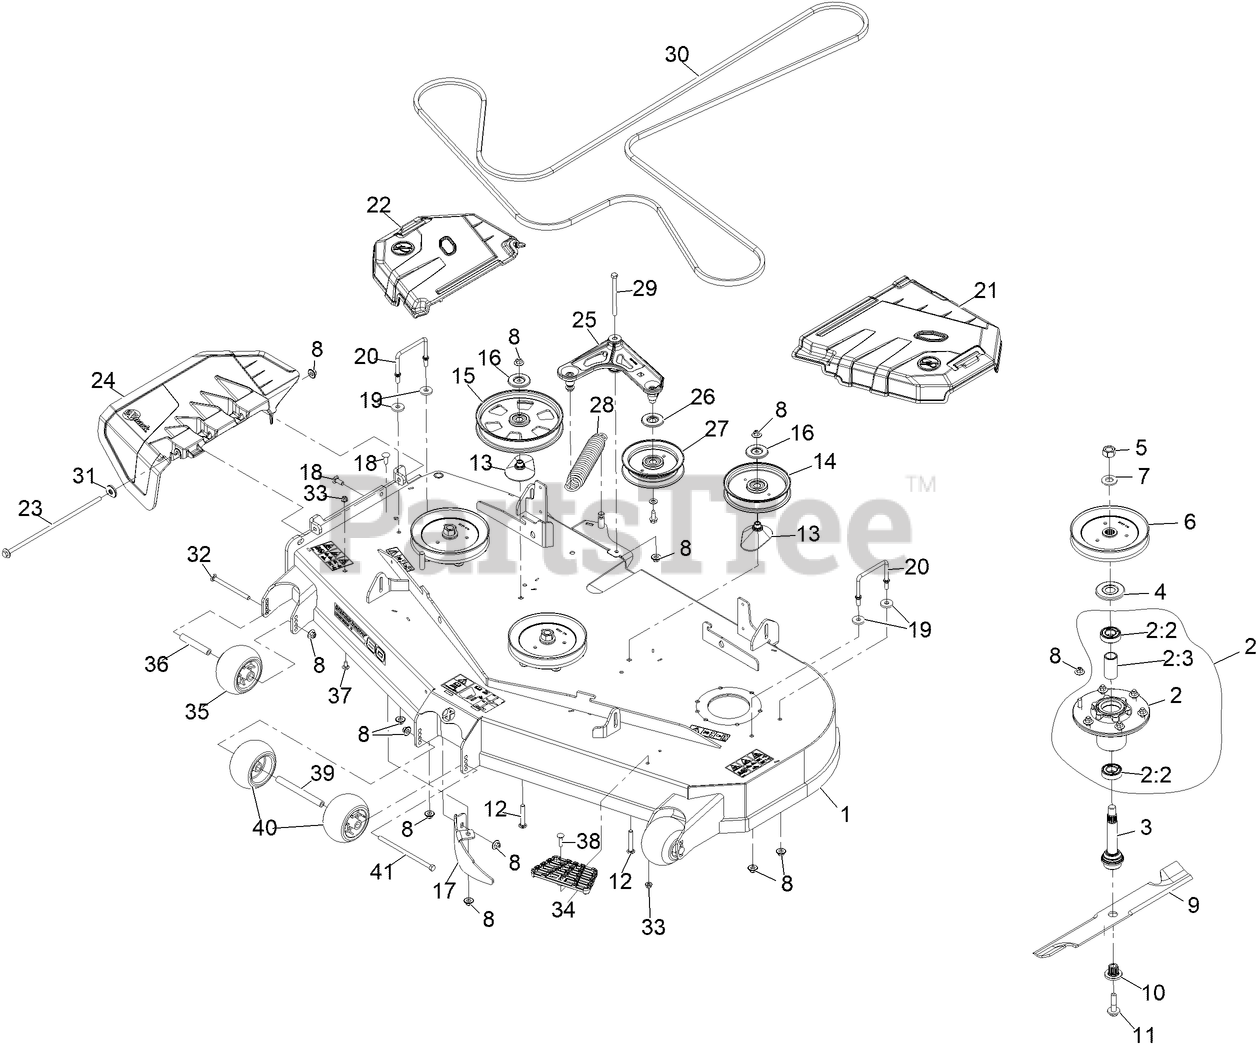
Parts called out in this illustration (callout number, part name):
1	ASM-Deck W/Decals
2	ASM-CUTTER HSG WITH BEARINGS
2:2	BEARING-BALL
2:3	SPACER-BEARING
3	ASM-SPINDLE AND SEAL
4	GUARD-BEARING, TOP
5	NUT-HEX
6	SHEAVE,BLADE DRIVE 7.25
8	Nut-Nyloc 3/8-16 Flg
9	Blade-Extreme 2, 20.50"
10	BUSHING,SPLINED
11	SCREW,SEMS 1/2-20 X 2.19
12	SCREW-CARR
13	SPACER-PULLEY
14	IDLER-PULLEY, FLAT 6.00X1.00
15	PULLEY-IDLER, FLAT
16	SHIELD-DUST
17	DOGLEG - LZ60
18	SCREW-CARR
20	WIREFORM-COVER
21	SHIELD, LT
22	SHIELD, RT
23	Pin, Chute
24	Chute-Deck Discharge
25	ASM-IDLER ARM W/BEARINGS
26	SHIELD-GUARD, DUST
27	IDLER-PULLEY, FLAT
28	SPRING-EXTENSION
29	SCREW-HH
30	Belt, B Section
31	Retainer, Chute
32	BOLT-CARR
33	NUT-HF, NI
34	STEP-DECK
35	ROLLER-SCALP, ANTI
36	SPACER-AXLE
37	SCREW-CARR
38	Bolt-Carriage 5/16-18 X 1 1/4
39	SPACER-WHEEL
40	ROLLER-SCALP, ANTI
41	SCREW-HH
